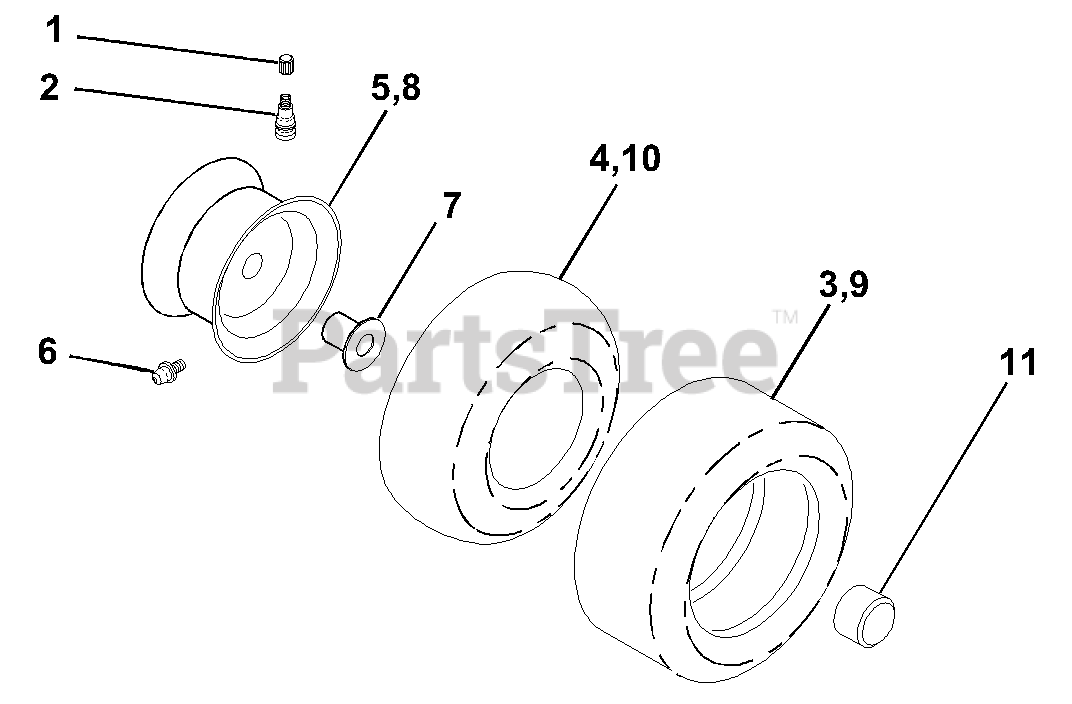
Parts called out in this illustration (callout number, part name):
1	Cap Valve Tire
2	Stem Valve
3	Tire F Ts 15 X 6 0 - 6 Service
4	Tube Front
5	Rim Asm 6" front Service
6	Fitting Grease
7	Bearing Flange
8	Rim Asm 8" rear Service
9	Tire R Ts 20 x 10-8 C Service
10	Tube Rear
11	Cap Axle Blk 1 50 X 1 00
